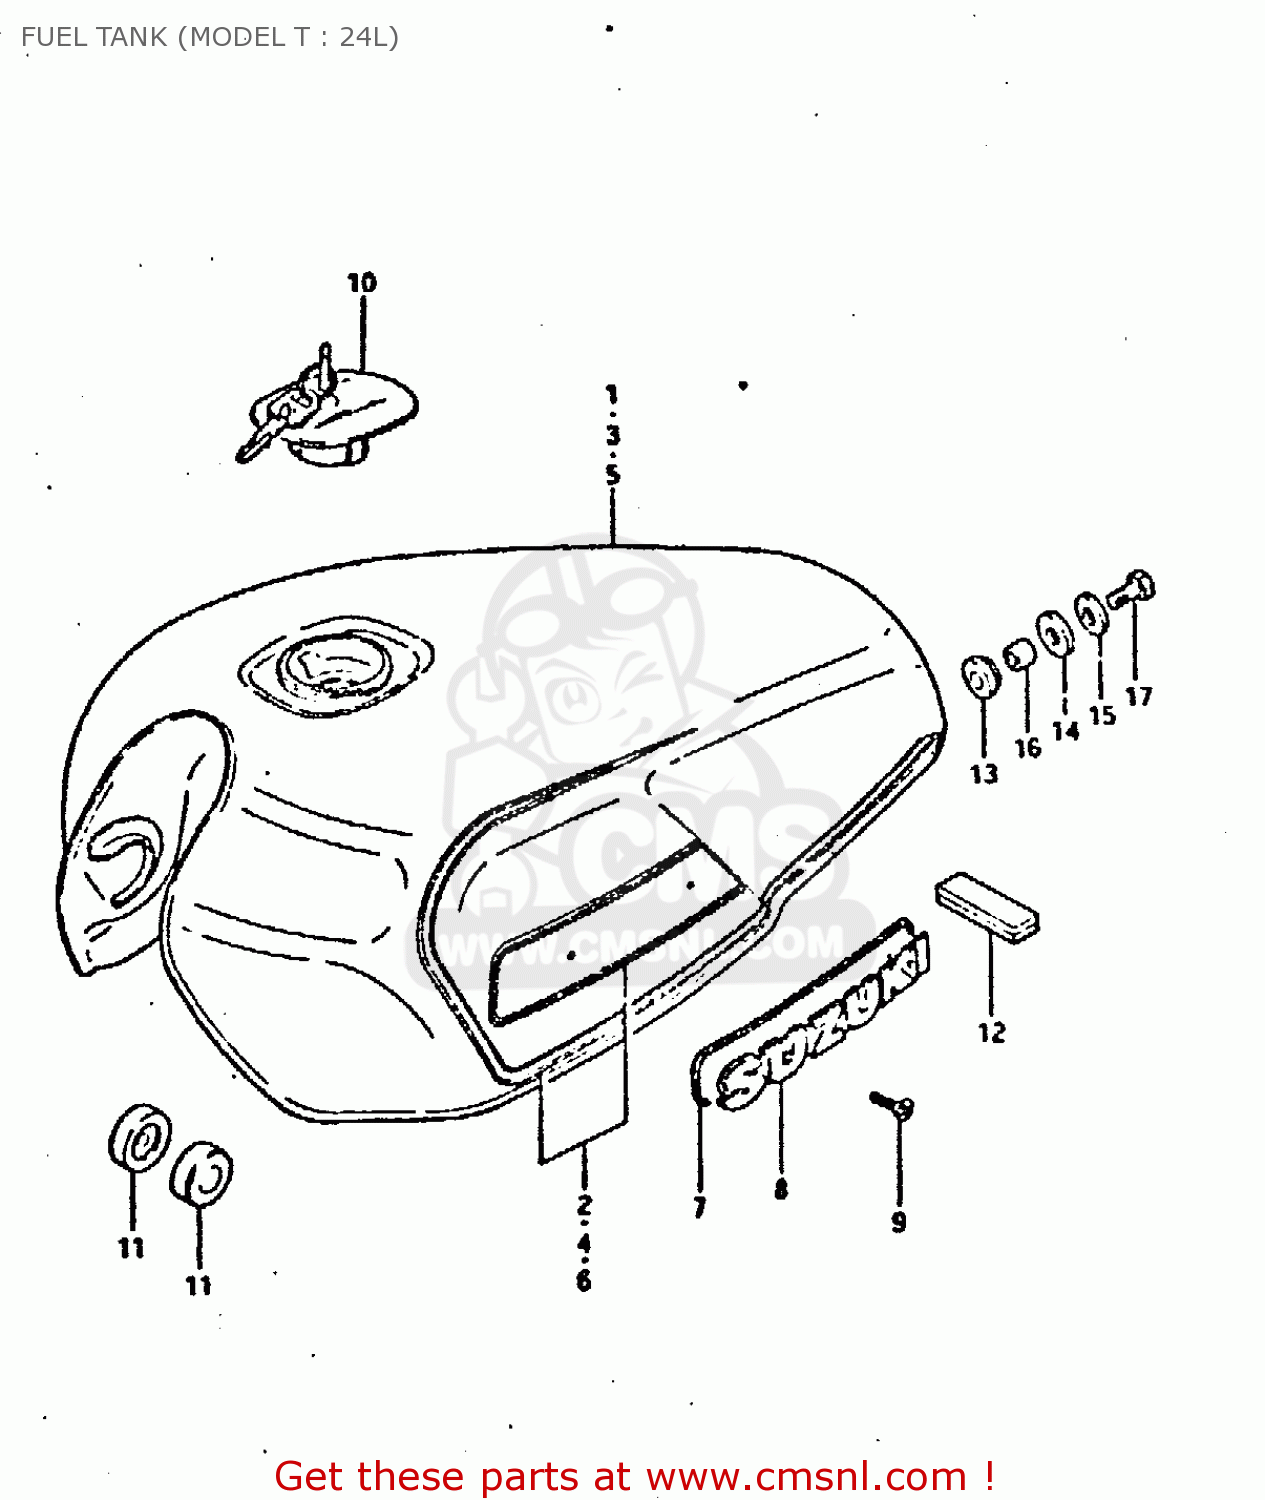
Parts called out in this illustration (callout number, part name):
1	TANK, FUEL (BLACK)
2	TAPE SET
3	TANK, FUEL (RED)
4	TAPE SET
5	TANK, FUEL (BLUE)
6	TAPE SET
8	EMBLEM,FUEL TANK
9	SCREW 3X6
10	CAP SET,FUEL TANK
11	CUSHION
12	CUSHION
13	CUSHION
14	CUSHION
15	WASHER (8.5X29X1.6)
16	SPACER(8.5X12X19)
17	BOLT (8X30)
